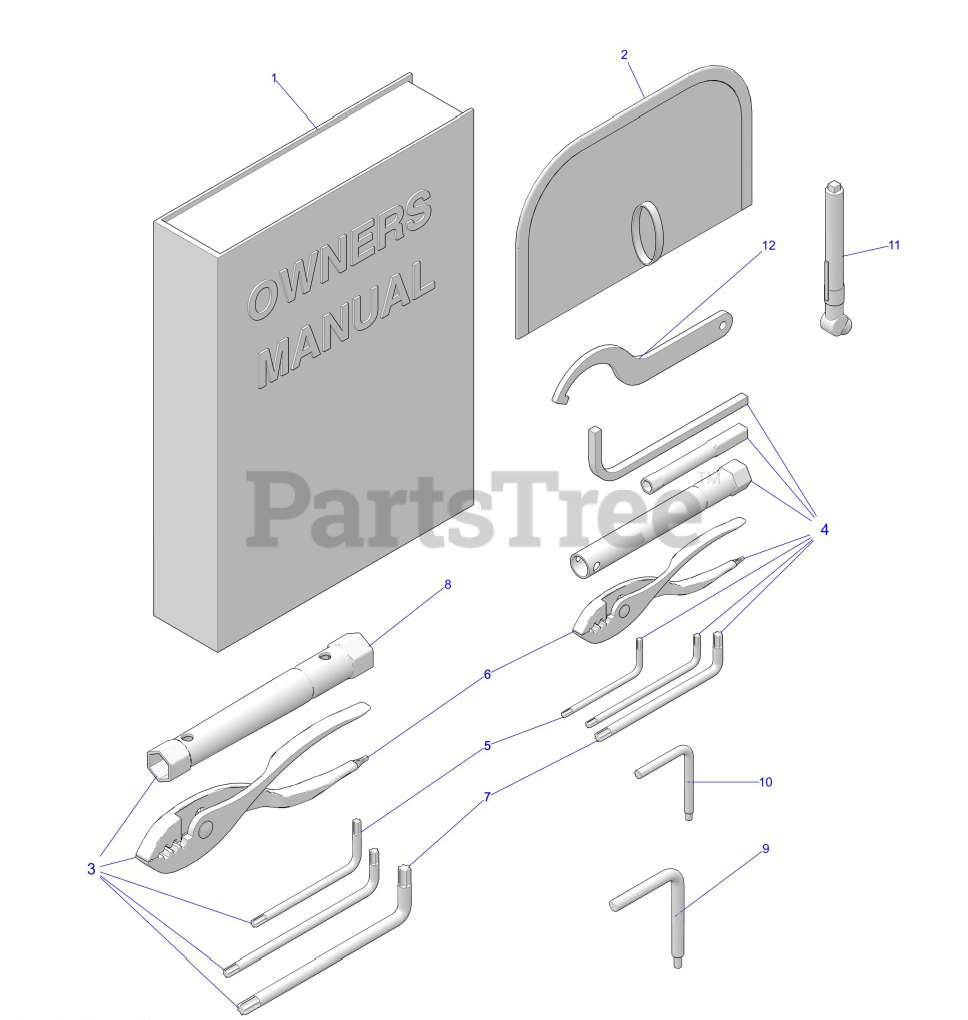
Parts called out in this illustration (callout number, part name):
2	POUCH,TOOLKIT,9"
3	Vehicle Toolkit (Multi-Function Pliers & Torx Wrenches)
4	KIT, TOOL
5	WRENCH-TORX,T-25
6	PLIERS-COMBO, #2 ASSEMBLY
7	WRENCH-TORX,T-40
9	Drive Clutch Separator Tool
10	TOOL-BELT REMOVAL
11	GAUGE-TIRE PRESSURE,30 PSI
12	WRENCH-SPANNER, CAM
